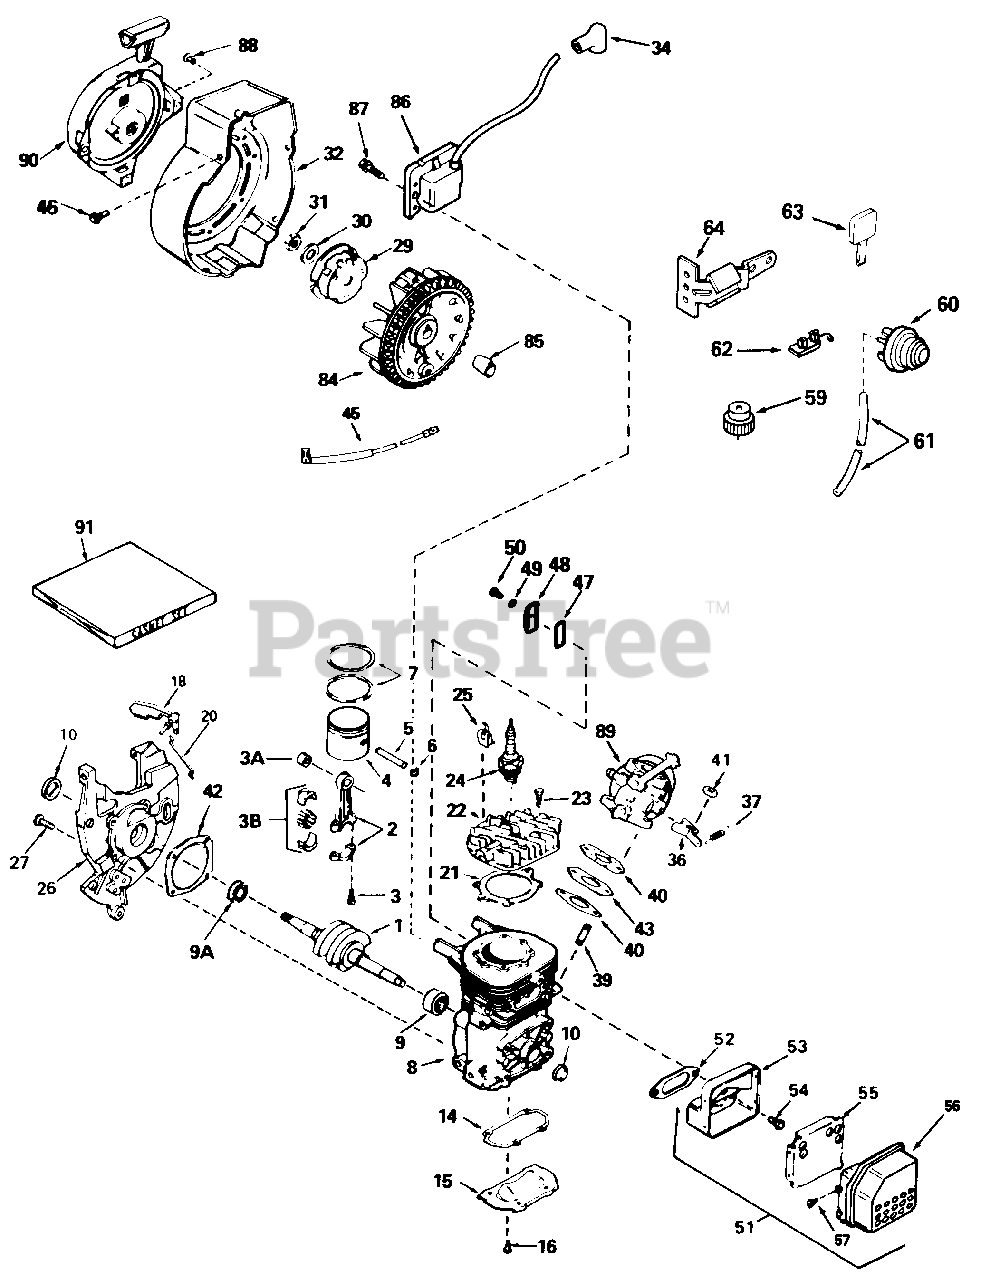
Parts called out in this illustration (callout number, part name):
1	Crankshaft
2	Rod Ass'y., Connecting
3	Screw, Connecting Rod
3A	Bearing, Cartridge
3B	Bearing & Liner Set, Needle (37 Needles)
4	Piston
5	Pin, Piston
6	Ring Piston Pin Retaining
7	Ring Set, Piston
8	Block Ass'y. Cylinder
9	Bearing, Needle
9A	Bearing, Ball
10	Seal, Crankshaft
14	Gasket, Cover
15	Plate,Cover
16	Screw, Pan Flex Hd., 10-24X 1/2
18	Vane Ass'y., Air
20	Link, Governor
21	Gasket, Cylinder Head
22	Head, Cylinder
23	Screw, Pan Flex Hd., 1/4-20 x 3/4
24	Plug, Spark
26	Base Ass'y., Blower Housing
27	Screw, Hex Hd., 1/4-20 x 5/8
29	Cup, Starter
30	Washer, Spring
31	Nut Flywheel
32	Housing, Blower
34	Cover, Spark Plug
36	Lever, Adjusting
37	Spring, Adjusting Lever
39	Stud Carburetor
40	Gasket, Carburetor
41	Nut, Hex 1/4-28
42	Gasket, Housing Base
45	Wire, Ground
46	Screw, Hex Washer Hd. Powerlok Thread, 1/4-20 x 3/8
47	Gasket, Cover
48	Cover Ass'y., Compression Release
49	Washer, Flat No. 10
50	Screw, Pan Flex Hd., 10-24 X 1/2
51	Muffler Ass'y.
52	Gasket, Muffler
53	Base, Muffler
54	Screw, Hex Washer Hd., 1/4-20 x 5/8
55	Baffle, Muffler
56	Cap, Muffler
57	Screw, Hex Hd. Self-Tap, 8-18 x 3/8
59	Cap Ass'y., Fuel
60	Primer Ass'y.
61	Primer Line
62	Terminal Ass'y.
64	Bracket Key S witch
85	Sleeve, Flywheel
86	Solid State Ass'y.
87	Screw, Hex Hd. Sems, 10-24 x 1
88	Rivet Pop (3/16" Dia.)
89	Carburetor
90	Starter Ass'y., Rewind
91	Gasket Set
